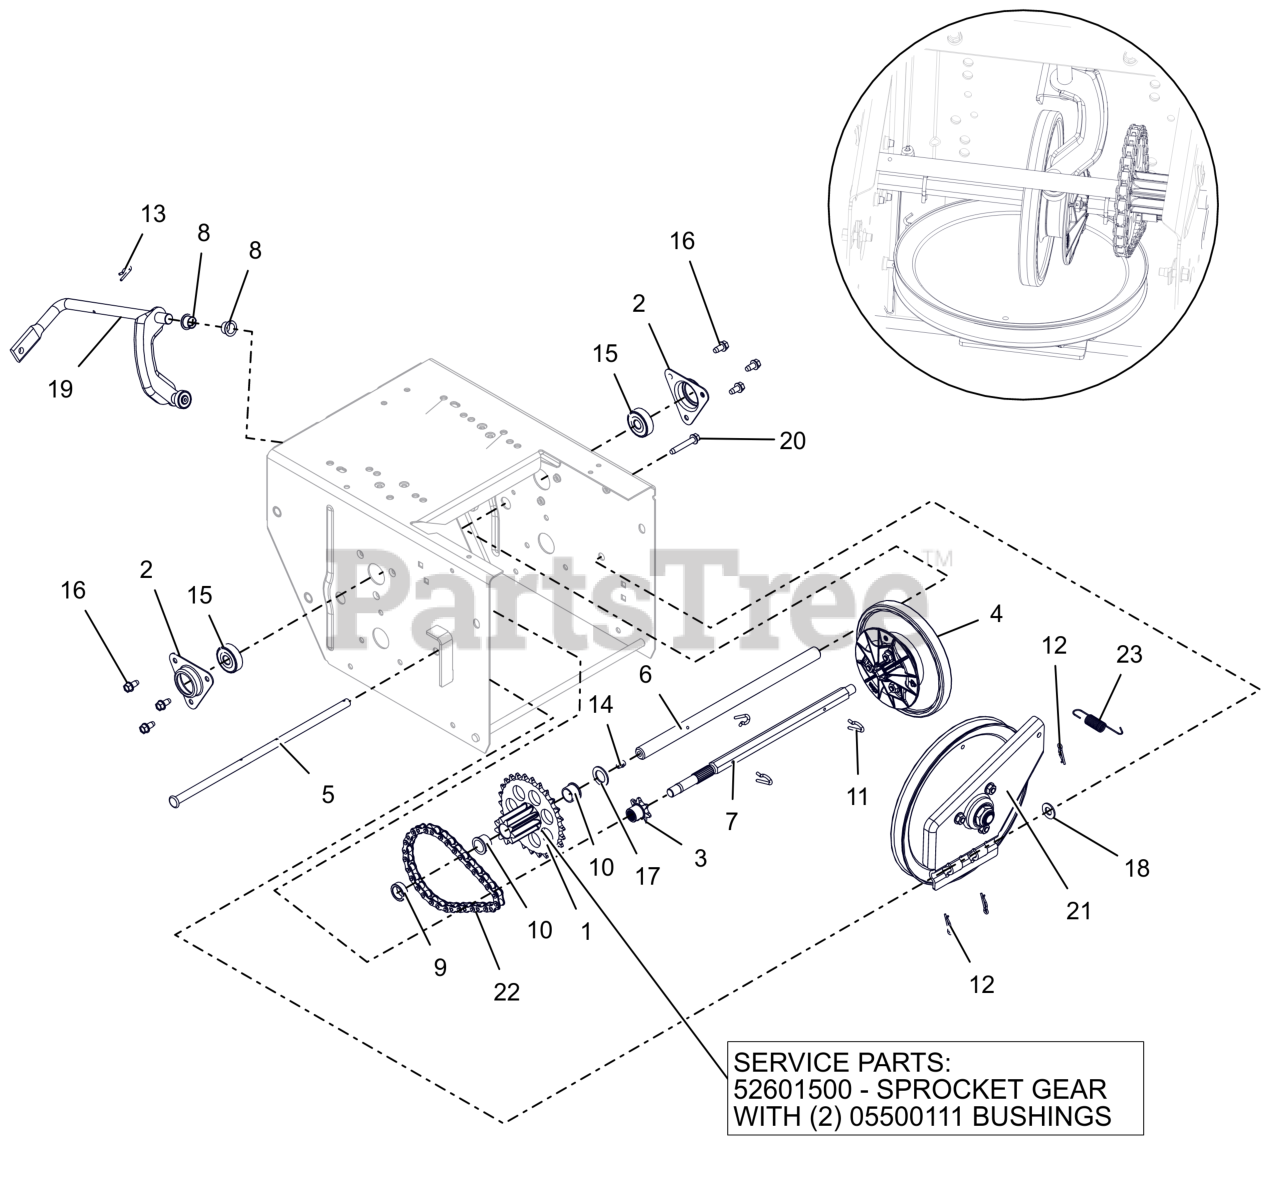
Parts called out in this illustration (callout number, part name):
1	PINION & SPROCKET
1	PINION & SPROCKET W/BUSHINGS
2	FLANGE, BEARING
3	SPROCKET, PINION 7T W/SPLINE
4	DISC, FRICTION DRIVE-ASSEMBLY
5	PIN, PIVOT
6	SHAFT, PINION
7	SHAFT, HEX
8	BUSHING, POLYLINER-.50 SPLIT
9	BSHG-SLV, .635X.880X.305
10	BSHG-FLG .625X.750X.500X.875
11	PIN, SPRING CLIP
12	PIN, HAIR #225 .072X1.09
13	CLIP, SPRING
14	ZERK,FITTING .25X.125 DRIVE IN
15	BRG-BALL .437X1.375X.437
16	SCR-TAP .25-20X.50 HWH ZCC
17	WSHR, FLT .630X1.005X.062 ZCC
18	WSHR,FLT .406X.812X.065 ZCC
19	ARM, SHIFT - ASSEMBLY
20	SCR,TAP .25-20X1.50 HWH TR ZCC
21	PLATE, SWING ASSEMBLY-DEEP
22	CHAIN - #41, 32 PITCHES
23	SG-TENS .048X.50X2.8
